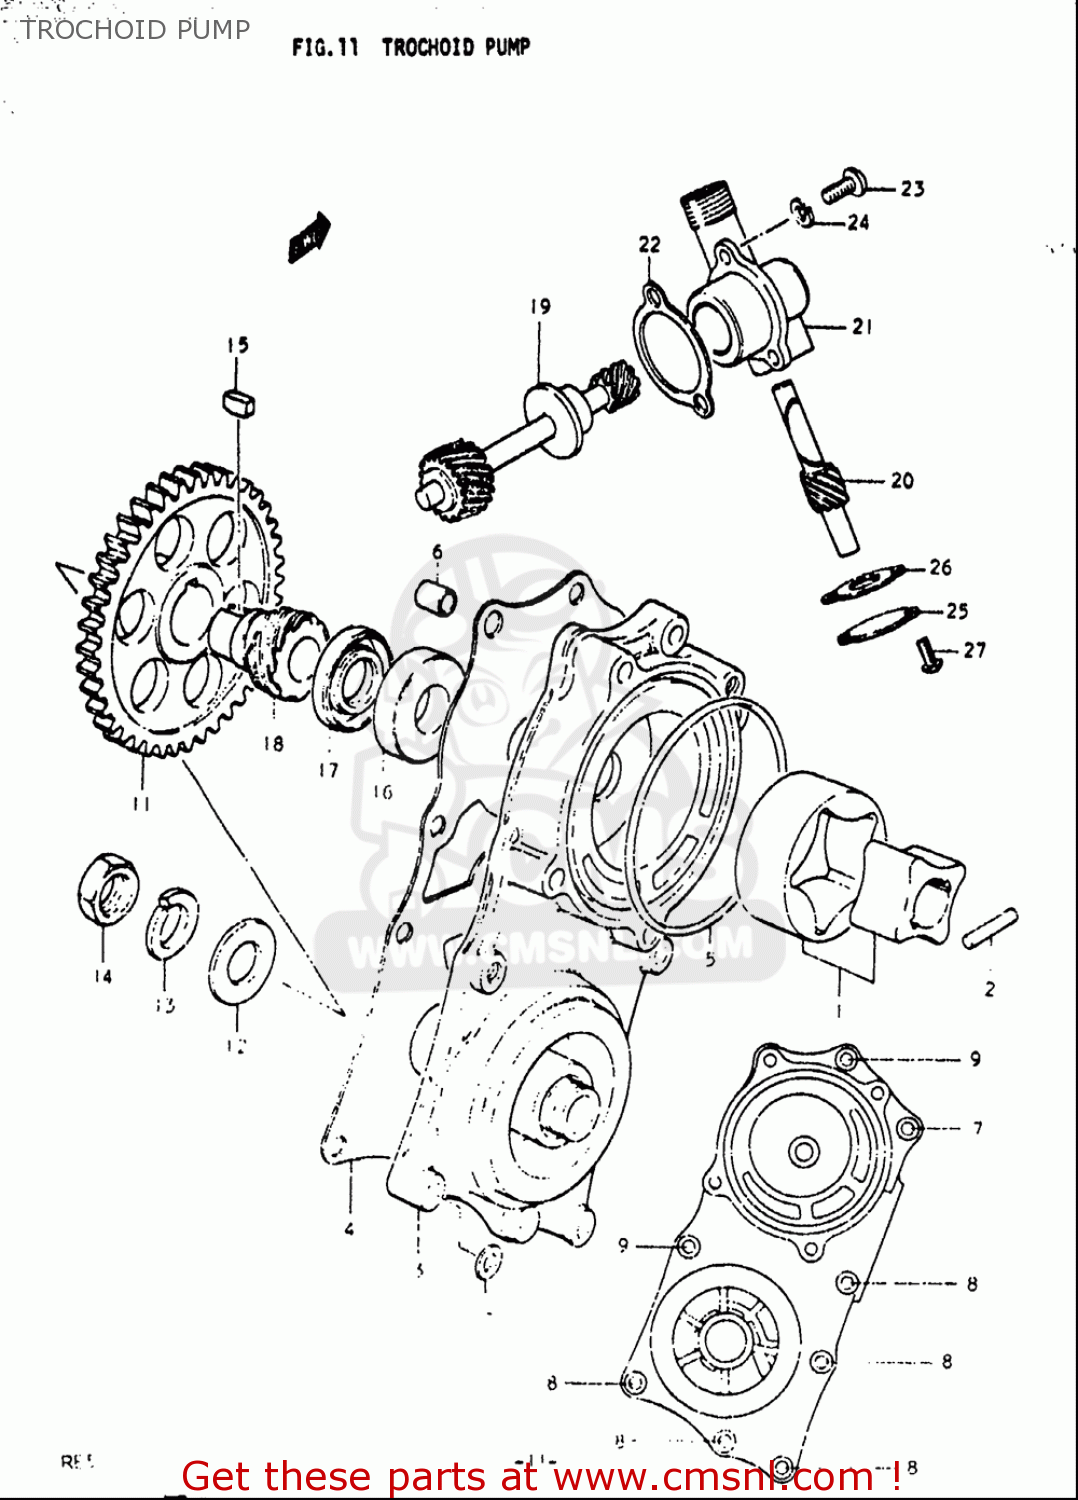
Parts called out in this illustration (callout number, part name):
2	PIN(4X20)
5	O RING(D:3.1,ID:71)
6	PIN
9	BOLT
10	WASHER
12	WASHER(12.5X26X1.6)
13	WASHER,LOCK
14	NUT
23	SCREW
24	WASHER,LOCK
27	SCREW
